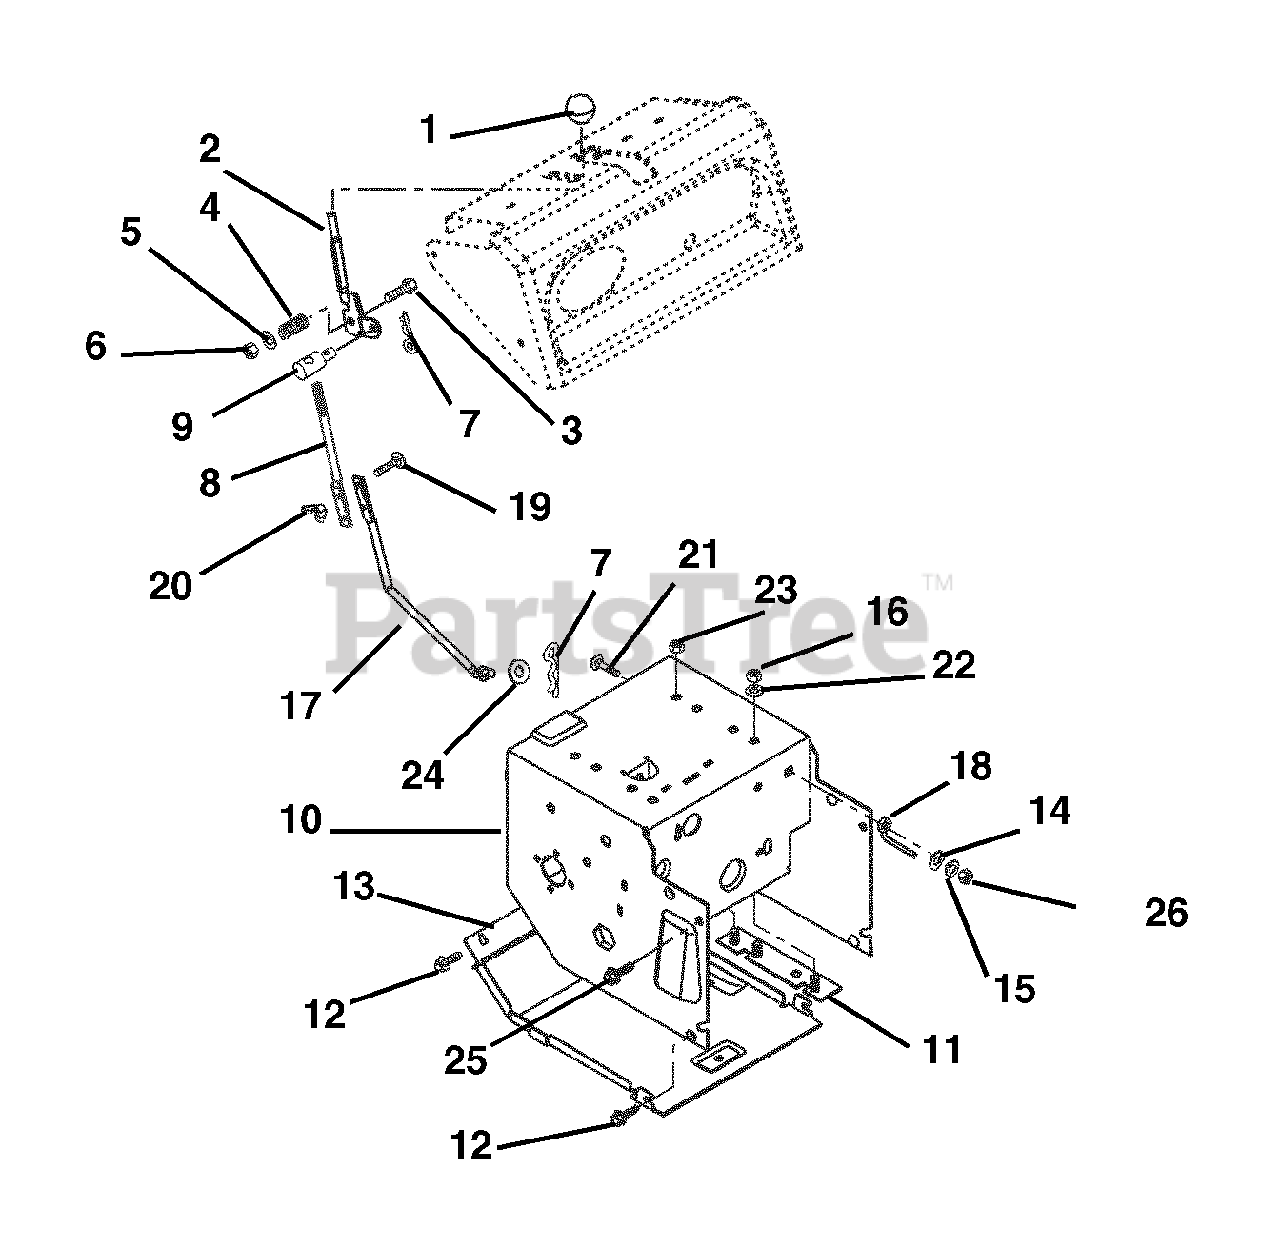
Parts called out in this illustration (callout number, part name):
1	KNOB,BALL -BLACK 1.47" .375-16
2	LEVER, SHIFT
3	@BLT-HEX .38-16X2.00 GR5 YWZC
4	SG-COMP .125X.781X1.250
5	@WSHR-FL-STL.438X1.00X.083 YWZ
6	@NUT-LK-CTR .38-16 YWZC
7	PIN-HAIR INT .08X.18X1.18 YWZC
8	ROD, SHIFT-UPPER
9	PIVOT, ROD (TRUNNION ) .50
11	ENGINE MOUNT, 5L,7L,8R
12	@SCR-TAP .25-20X.37 HWH YWZ TR
13	COVER BOTTOM
14	@WSHR-FL-STL.38X.875X.083 YWZC
15	@WSHR-LK .31X.078 REG YWZC
16	@NUT-HEX .31-18 YWZC
17	ROD, SHIFT-LOWER
18	BELT FINGER LOWER
19	@BLT-RDHDSQNK .25-20X1.00 G5YZ
20	NUT-LK WING .250-20 YWZC
21	@BLT-RDHDSQNK .31-18X1.00 G5YZ
22	WSHR-LK .312X.097 HVY YWZC
23	@NUT-LK-NYL .312-18 YWZC
24	@WSHR-FL-STL.531X1.06X.095YWZC
25	@SCR-TAP .38-16X.75 HWH TR YWZ
26	@NUT-HEX .31-18 YWZC
